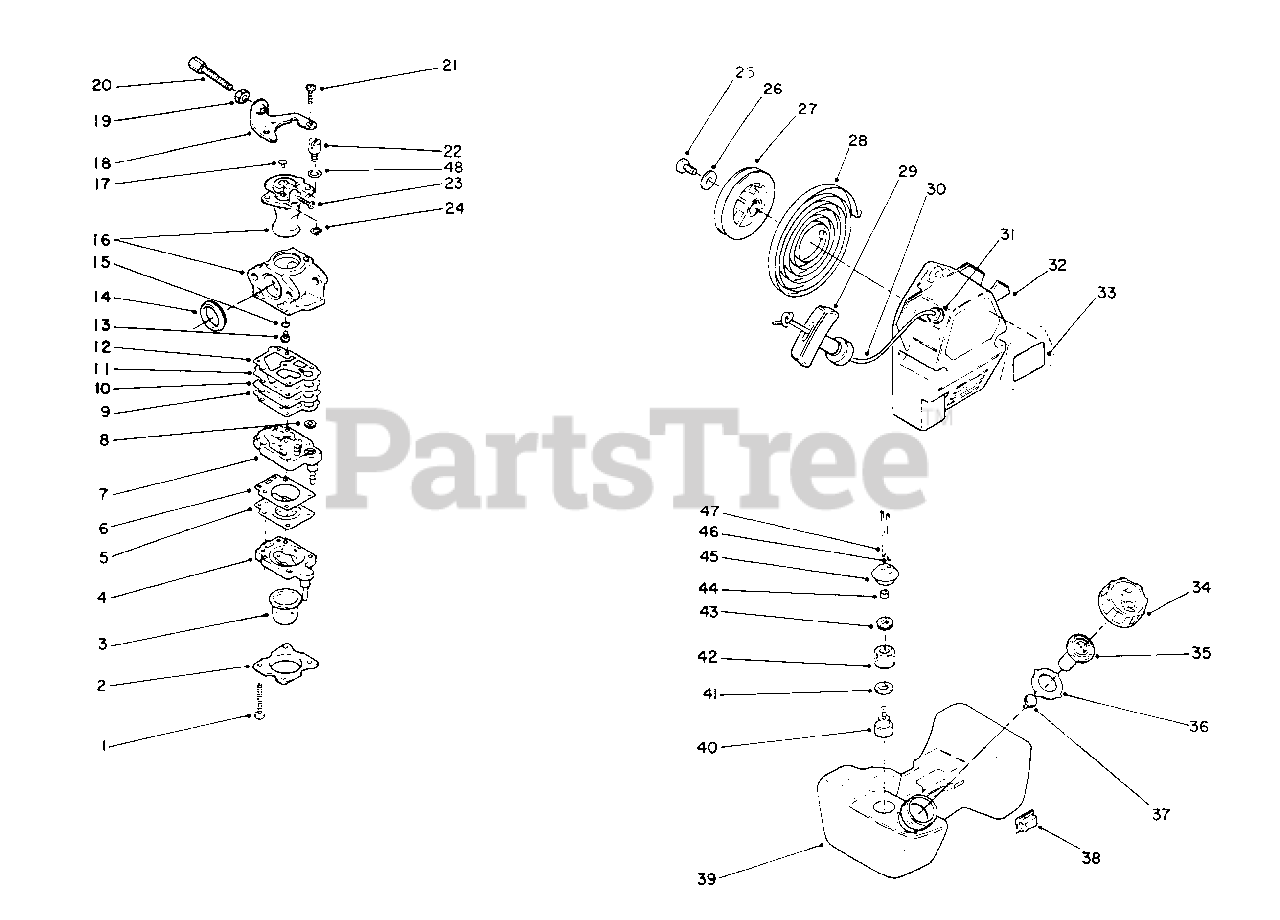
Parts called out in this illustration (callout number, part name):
2	Cover-Primer
3	Bulb-Primer
4	Body-Primer
5	Diaphragm
6	Gasket-Diaphragm
7	Body Ass'y-Pump (Incl. Ref. #8)
9	Gasket-Pump
11	Diaphragm
12	Gasket-Diaphragm
13	Jet-Main #43
15	"O"Ring-Main Jet
16	Body-Carburetor (Ref.)
18	Bracket-Throttle
19	Nut-Lock
20	Screw-Adjustment
22	Swivel-Cable
23	Valve-Throttle
29	Handle-Recoil
30	Rope-Recoil
31	Guide-Rope
32	Case-Recoil
33	Decal-Toro
34	Cap-Fuel
35	Valve-Breather
37	Cap-Valve
39	Tank Assembly-Fuel (Incl. Ref. #34-37 & 40-47)
40	Weight-Filter
41	Washer-Seal
42	Filter-Fuel
43	Washer-Seal
45	Grommet-Fuel Tank
46	Hose-Fuel
47	Tube-Fuel Return
